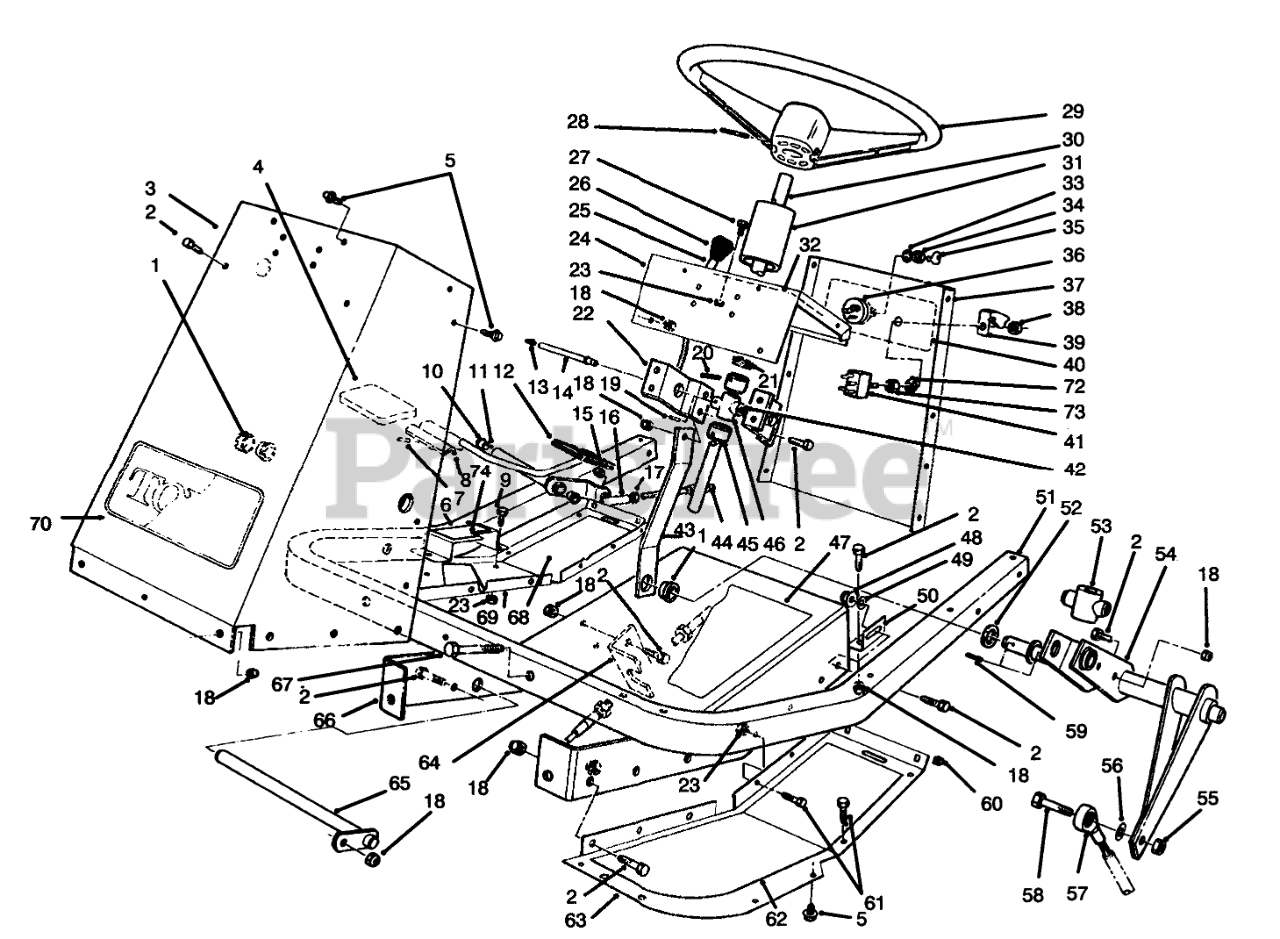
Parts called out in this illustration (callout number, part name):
1	BEARING-FLANGE
2	SCREW-HH
3	Tower-Front
4	FORWARD PEDAL PAD
5	SCREW-HHFTF
6	Footrest-Pedal
7	PIN-ROLL
8	ACCELERATOR PEDAL
9	SCREW-HH
10	BUSHING-FLANGE
11	Pedal-Traction (Incl. Ref. #10)
12	REVERSE PAD
13	FITTING-GREASE
14	TUBE ZERK
15	NUT-LOCK
16	JOINT-BALL
17	NUT-JAM
18	NUT-LOCK, NI
19	3/32 X 9/16 ROLL PIN
20	PIN-SPRING
21	COVER-DUST
22	BRG SUPT BRKT
23	NUT-LOCK, NI
24	Tower-Top
25	CONTROL-CHOKE,THROTTLE
27	SCREW-HH
28	PIN-ROLL
29	Steering Wheel
30	STEERING SHAFT
31	STRG. SHAFT COVER
32	THROTTLE DECAL
33	Washer-Lock
35	KEY-IGNITION
36	Switch-Ignition (Incl. Ref. #33-35)
37	Panel-Tower Rear
39	COVER-PTO SWITCH
40	SWITCH DECAL
41	Switch-Clutch & Brake (Incl. Ref. # 38, 72 & 73)
42	WASHER-BELLEVILLE
43	Link-Steering
44	TRACT CONT.CABLE
45	STRG SHAFT COLLAR
46	BRG STEERING SHAFT
47	TUNNEL DECAL
48	NUT-HF
49	WASHER-PLAIN
50	TUNNEL BRKT
51	Frame-Footrest
52	WASHER-THRUST
53	STEER.SHAFT FOLLOWER
54	Follower Lever
55	NUT-LOCK, NI
56	WASHER-FLAT
57	BALL JOINT LH
58	SCREW-HH
59	PIN-ROLL
60	NUT-RETAINED
61	SCREW-HH
62	FOOT REST PAD LH
63	Footrest-L.H.
64	TRACT CABLE BRKT
65	PEDAL.SHAFT WA
66	Tunnel
67	SCREW-HH
68	FOOT REST PAD RH
69	Footrest-R.H.
70	DECAL
72	TAB-WASHER
73	NUT-HEX, SPECIAL
74	FOOTREST PAD
